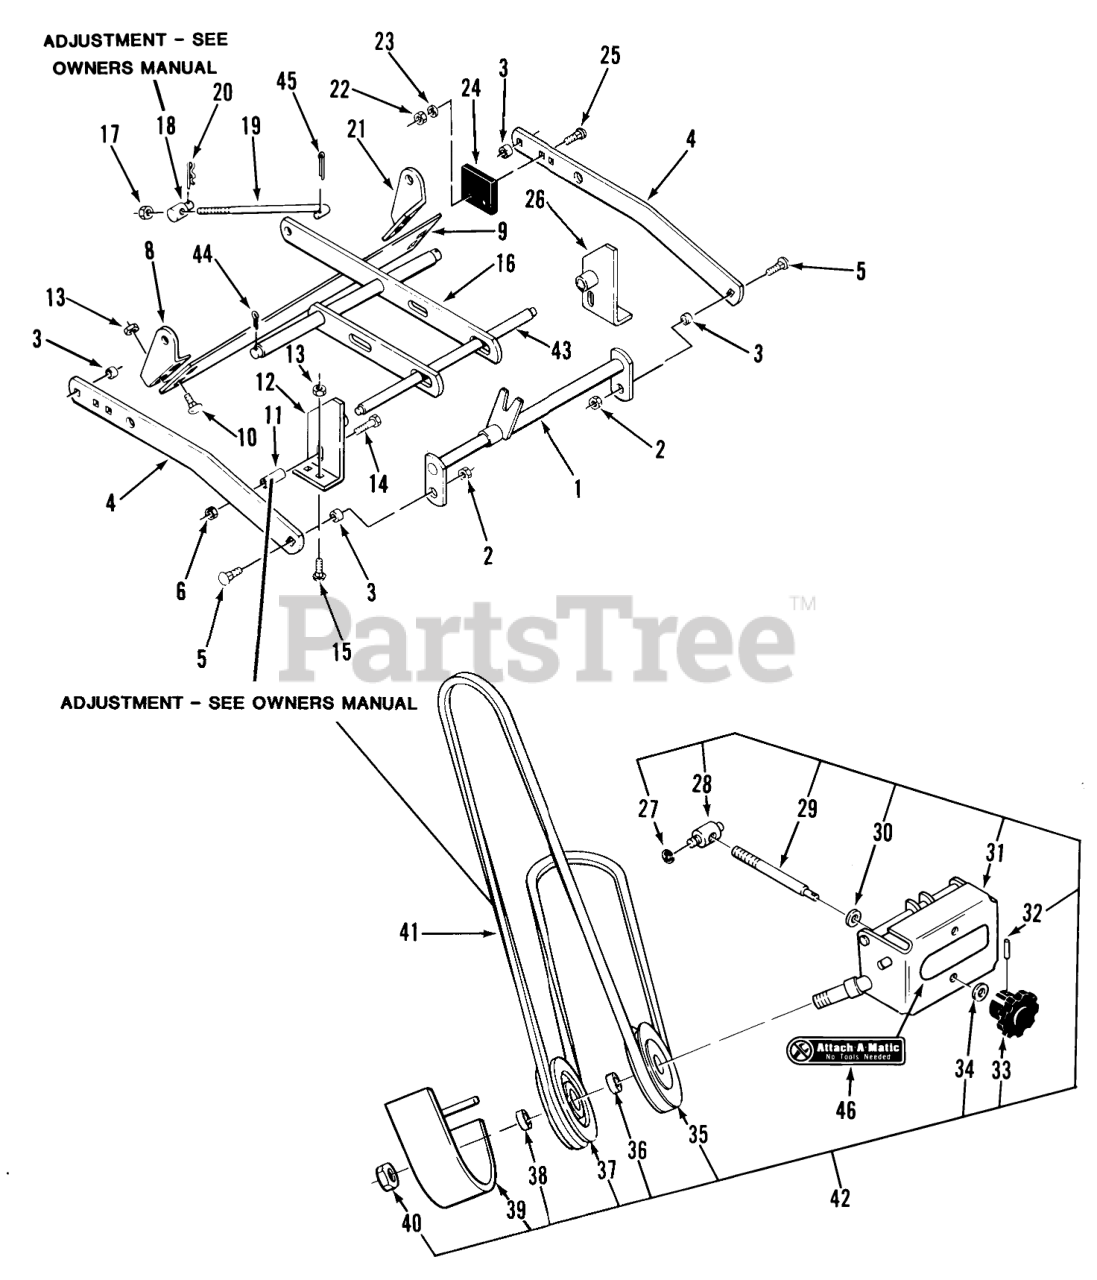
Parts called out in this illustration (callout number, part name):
1	Hitch
2	LOCKNUT-FLANGE
3	SPACER
4	Bar Draft
5	Bolt
6	Nut
8	Bracket-Rt. Rear
8	Bracket-R.H.
9	PLATE
9	PLATE R
10	Bolt
12	Bracket-R.H.
13	NUT
14	CARRIAGE BOLT -4
15	Bolt
16	Leveler
17	NUT
18	TRUNNION-LIFT
19	Lift Rod
20	Hairpin
20	SHAFT-ROLLER
21	Bracket-L.H. Rear
21	Bracket-L.H.
22	Nut
23	Collar
24	BUMPER
25	Bolt-Carriage
26	Bracket-L.H.
27	RING-RETAINING
28	TRUNNION-DOUBLE
29	ROD ADJ
30	Washer
31	Front Support
32	PIN-ROLL
33	KNOB-ADJUSTMENT
34	WASHER-SPRING
35	Pulley-V
36	SPACER
37	PULLEY-FLAT IDLER
38	SPACER-OUTER
39	Belt Cover
40	Nut
41	V-BELT
42	ASM-SUPPORT,IDLER
43	Front Shaft
44	Cotter Pin
45	Cotter Pin
46	Decal-Attac-O-Matic
